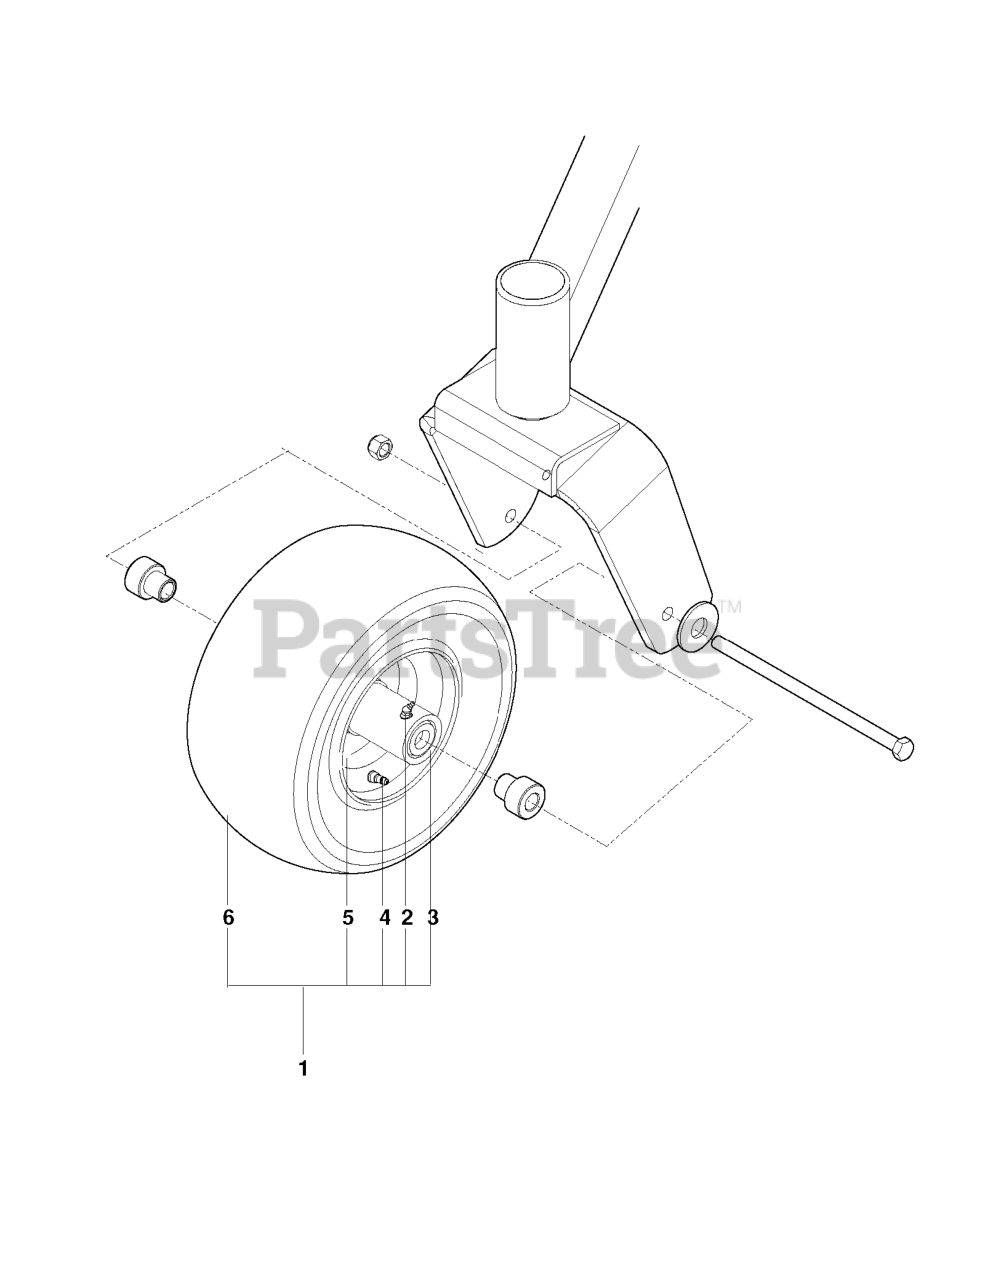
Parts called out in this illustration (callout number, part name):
1	TIRE.CASTER.ASSEM.11X4-5.GR
2	ZERK
4	VALVE STEM TR-412
6	TIRE - SMOOTH 13X6.50-6
